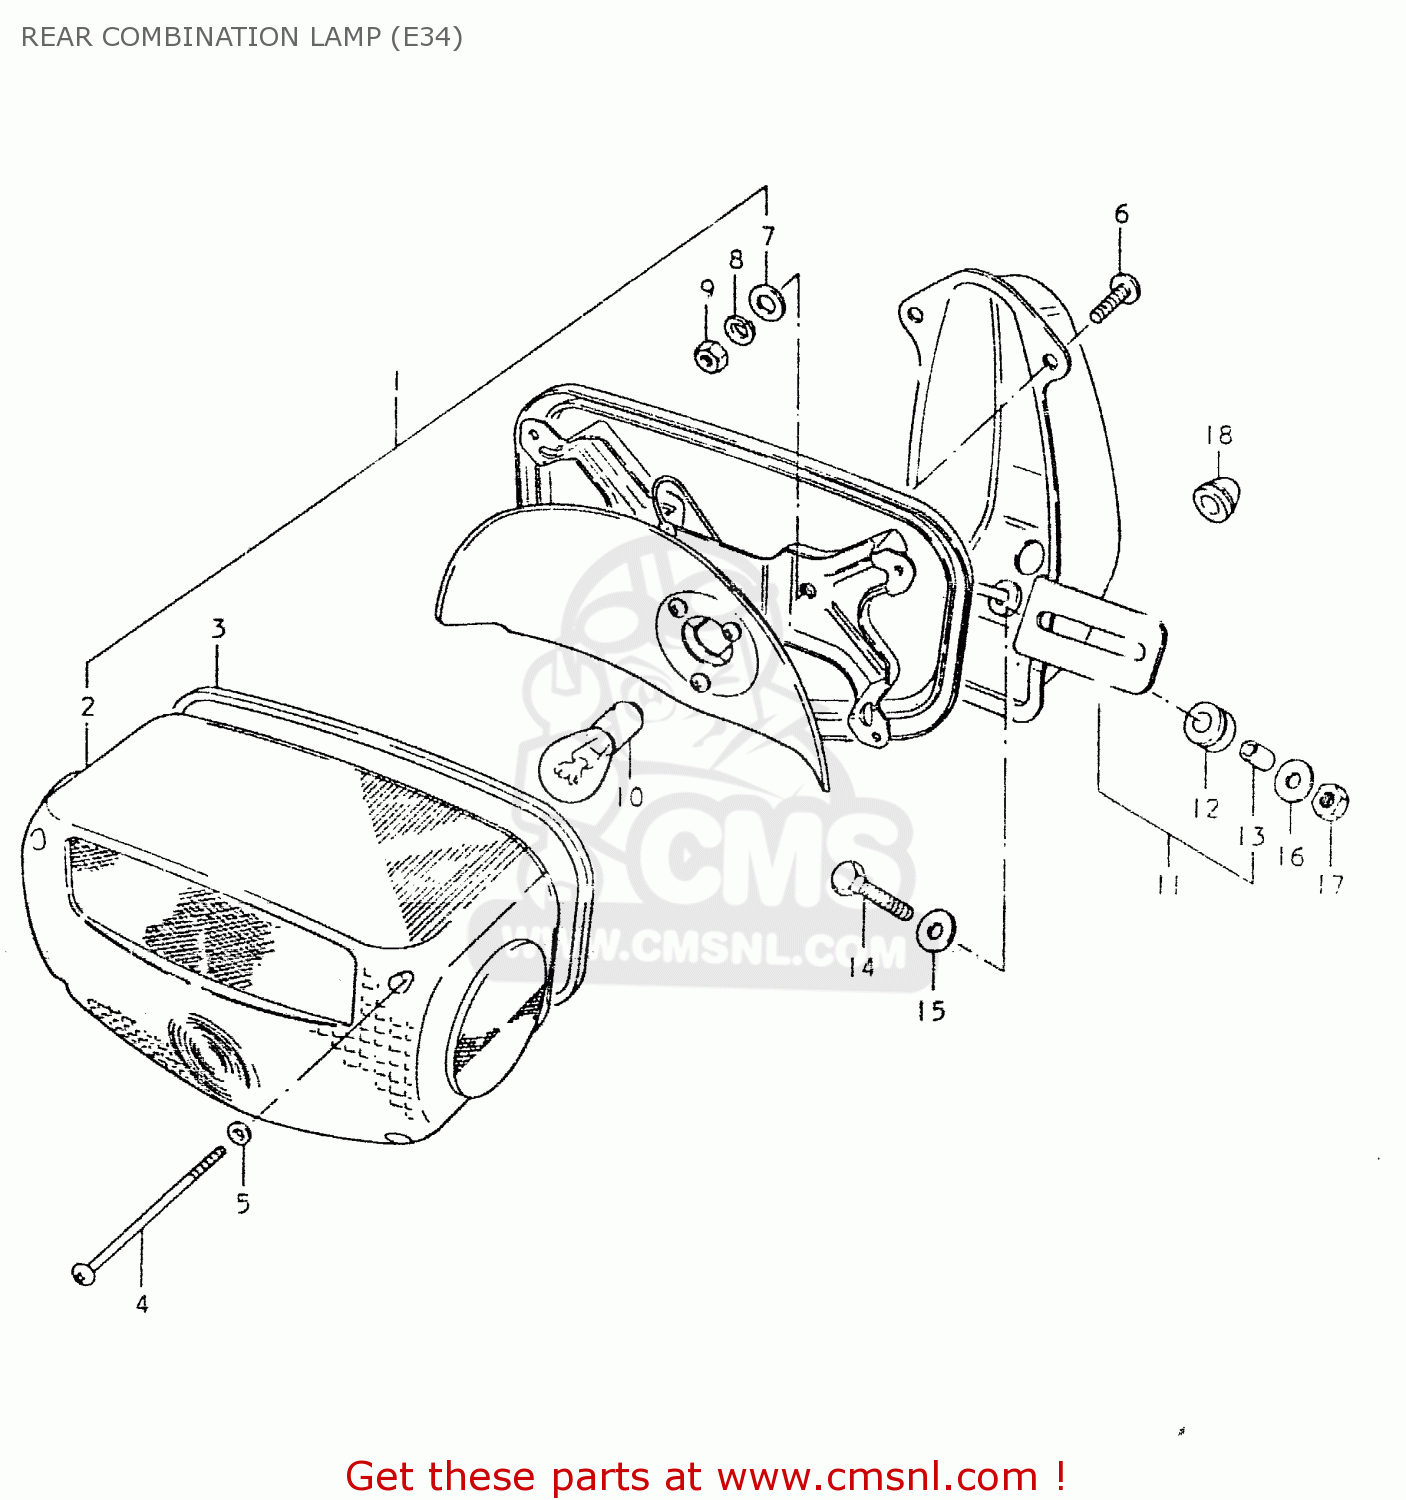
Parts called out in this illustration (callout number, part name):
1	LAMP UNIT, TAIL
2	LENS
3	GASKET (NAS)
4	SCREW (4X55)
5	GASKET (NAS)
6	SCREW 6X12
7	WASHER
8	LOCK WASHER
9	NUT
10	BULB(12V21/5W)
11	BRACKET ASSY
12	CUSHION
13	SPACER,REAR COMBINATION LAMP
14	BOLT
15	WASHER (6.5X20X1.2)
16	WASHER
17	NUT
18	GROMMET
